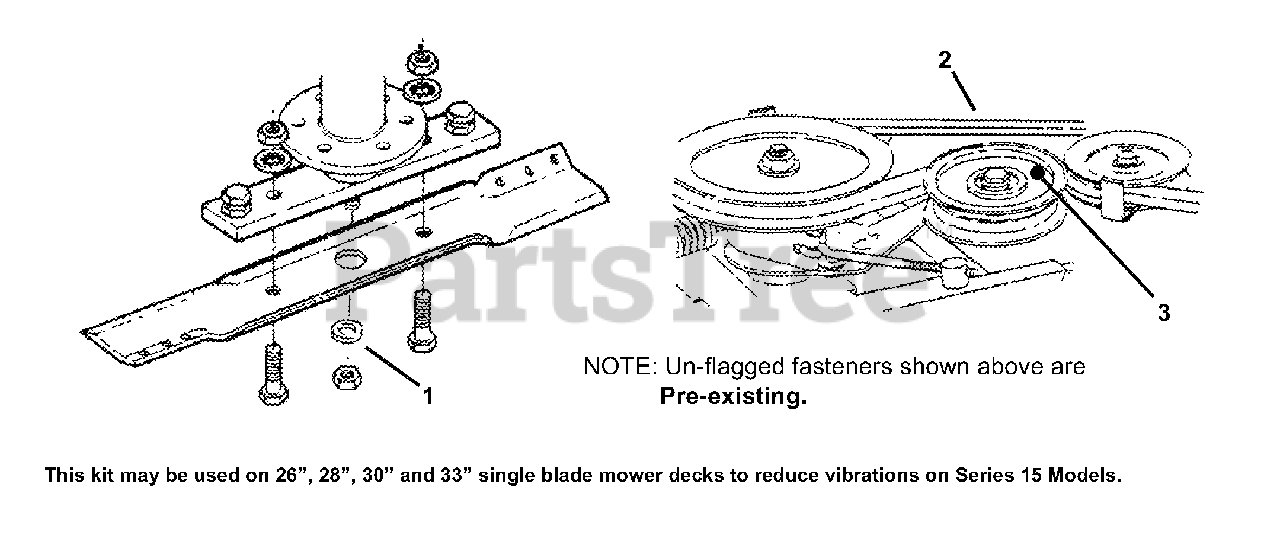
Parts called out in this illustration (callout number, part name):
1	SPACER, Blade Centering
2	BELT, Drive Deck (AA Section, 73.75" Effective Length)
3	PULLEY, Idler
